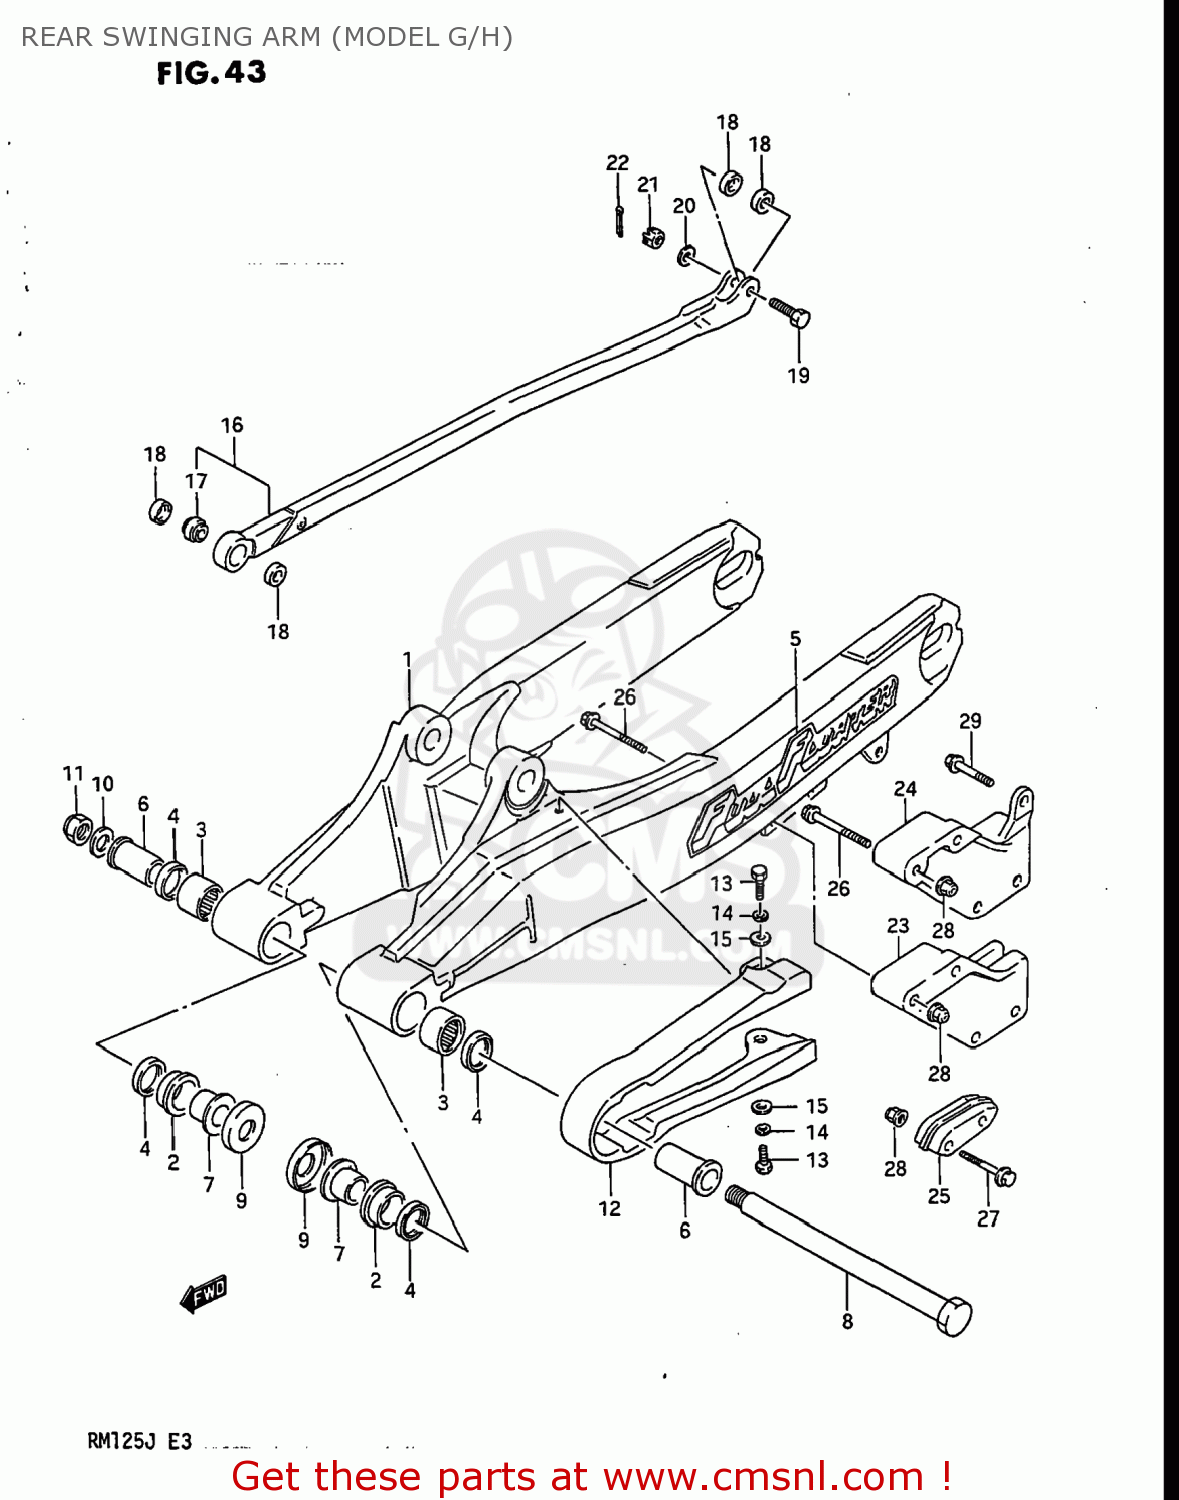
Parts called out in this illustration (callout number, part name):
1	SWING ARM ASSEMBLY,REAR
2	BUSH,RR SWINGINGARM PIVOT
3	BEARING(20X27X20)
4	OIL SEAL
5	LABEL (FRONT CARRIER WARNING)
6	SPACER,RR SWGARM PIVOT
7	SPACER,RR SWGARM PIVOT INNER
8	SHAFT,REAR SWING ARM PIVOT
9	COVER,RR SWGARM DUST SEAL
10	WASHER(14.2X24X2.3)
11	NUT
12	BUFFER,CHAIN TOUCH DEFLECTOR
13	BOLT
14	WASHER,LOCK
15	WASHER(6.5X16X1.2)
16	TORQUE LINK SET,REAR
17	SPHERICAL BEARING,TORQUE
18	19
19	BOLT 8X29.5
20	WASHER
21	NUT 8MM
22	PIN 20X20
23	GUIDE,CHAIN
24	GUIDE,CHAIN
25	DEFENSE,CHAIN GUIDE
26	BOLT
27	BOLT,UNDER
28	NUT
29	BOLT,REAR
